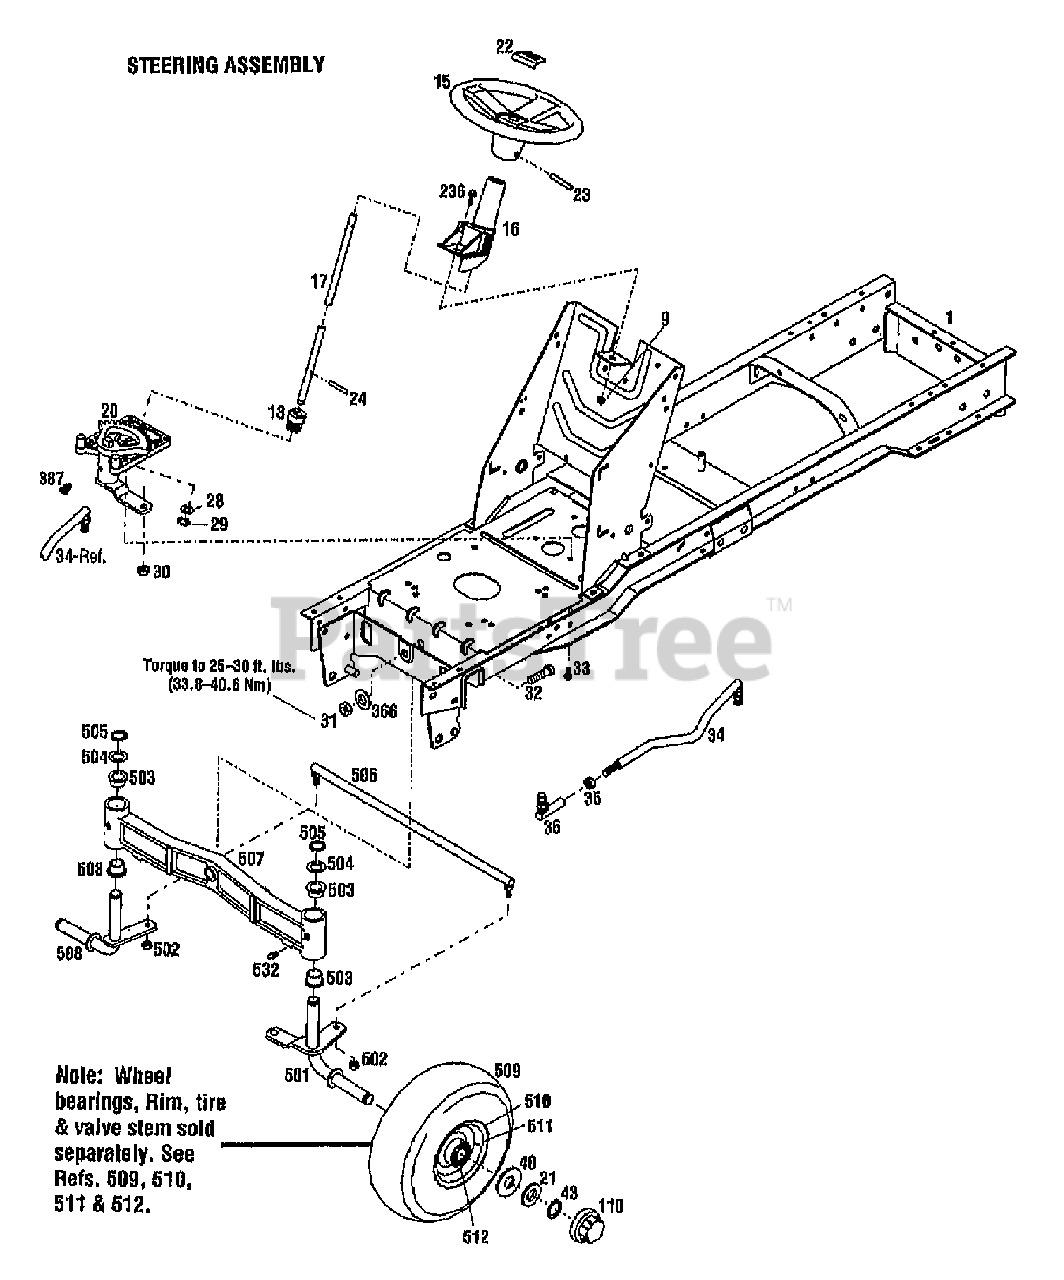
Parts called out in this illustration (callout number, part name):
9	NUT-HFLK 5/16-18 ZP
15	WHEEL-STEERING
16	SUPPORT-STEERING SHAFT
17	SHAFT-STEERING
18	GEAR-PINION
20	ASSM-STEERING GEAR
21	WASHER-THRUST
22	CAP-STEERING
23	PIN-ROLL .25X2.25
24	PIN-ROLL 1/4 X 1-1/4
28	WASHER-1.0X.64X.09
29	RING-RETAINING
30	NUT-HEX/JAM 1/2-20
31	NUT-H/LK 5/8-11
32	SCR-HH
33	SCR-HFLK 5/16-18X.75
34	LINK-DRAG
35	NUT-JAM
36	JOINT-BALL
40	WASHER-SPECIAL .75X2.5
43	RING-HEAVY EXT HD 1.0 ID
110	CAP-HUB
236	SCR-HFLK 5/16-18X.75 ZP
366	WASHER-1.75X.687X.134 ZP
387	FITTING-GREASE 90 DEGREE
501	SPINDLE-WHEEL LH
502	NUT-LOCK
503	BEARING-FLANGE
504	WASHER-THRUST
505	RING-HEAVY EXT HD 1.0 ID
506	KIT-TIE ROD W/HDW
507	AXLE-FRONT
508	SPINDLE-WHEEL RH
509	TIRE-16X6.50-8
510	RIM-WHEEL
511	STEM-VALVE
512	BEARING-BALL
532	FITTING-GREASE 1/4-28X2.00
